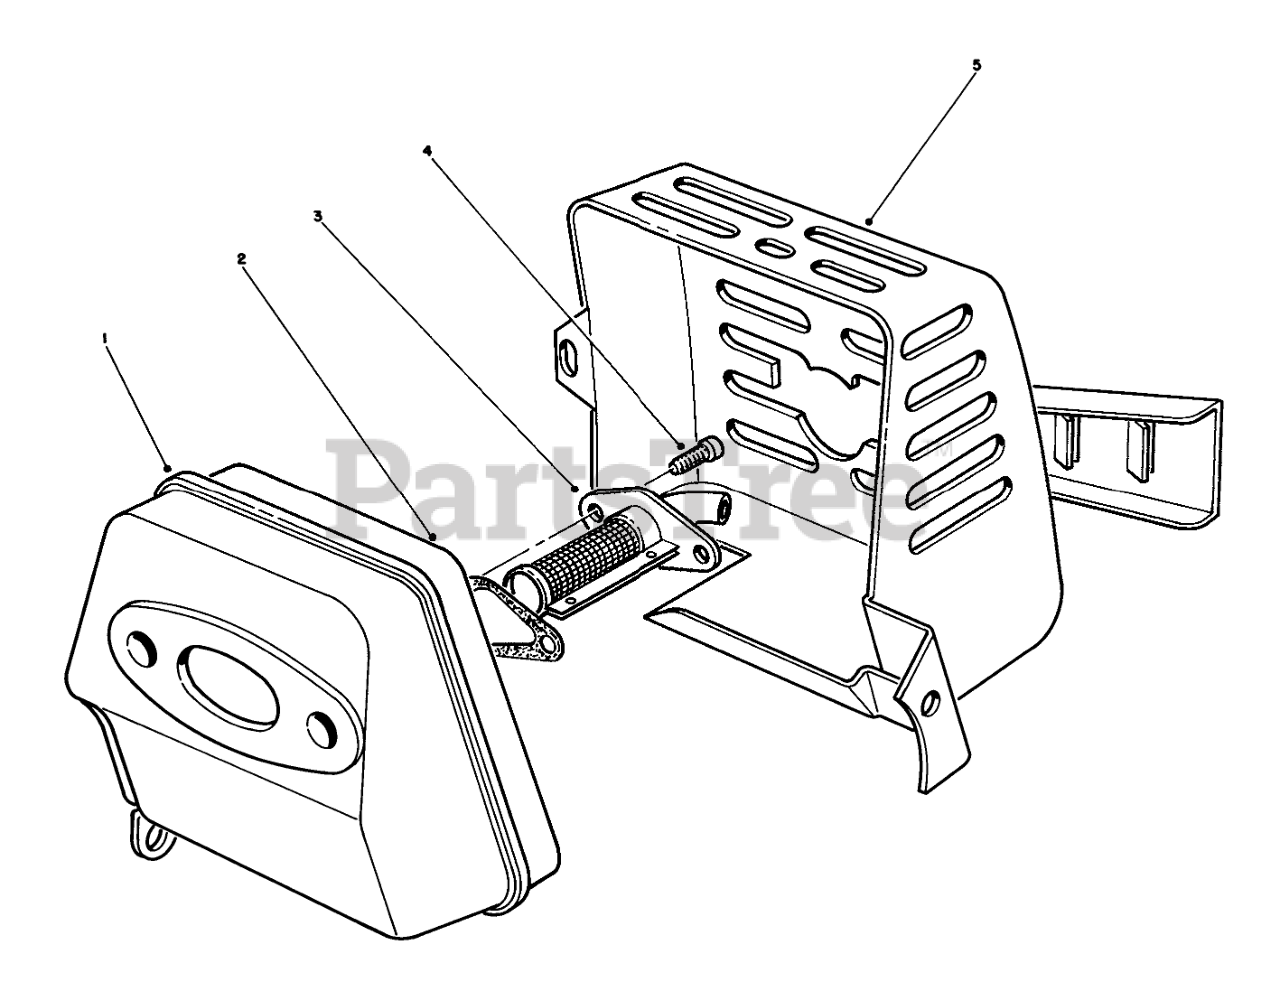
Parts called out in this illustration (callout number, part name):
1	Muffler
2	Gasket
3	Spark Arrestor
4	Screw & Washer
5	Cover-Muffler
